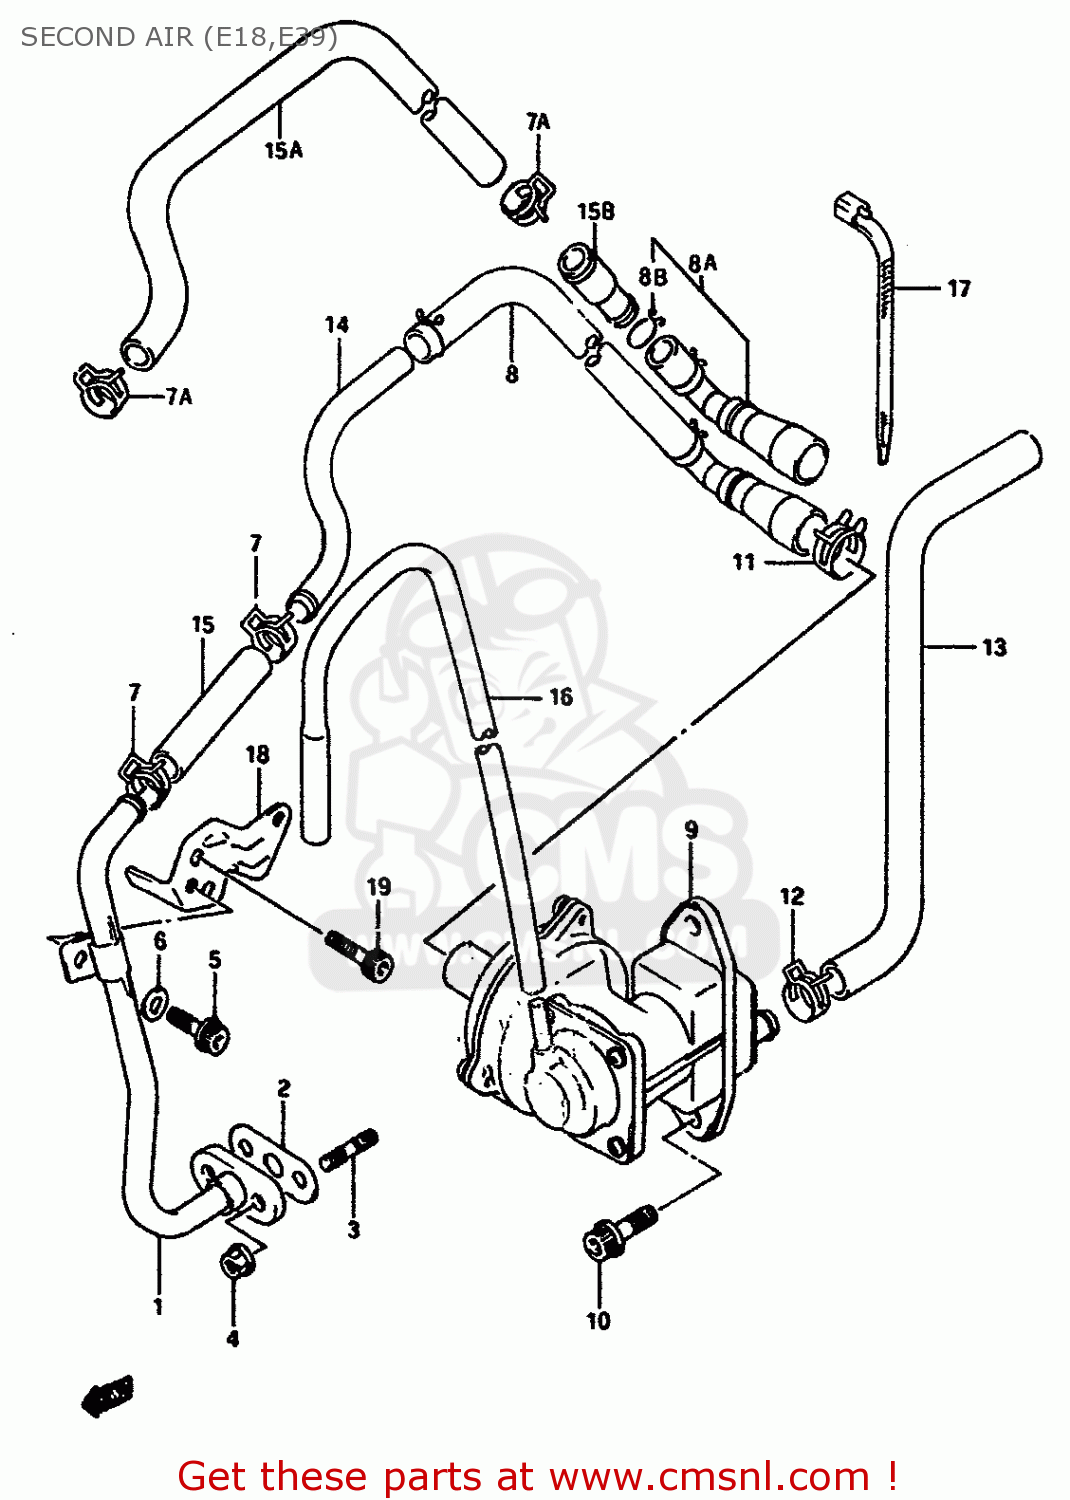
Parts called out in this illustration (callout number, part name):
1	PIPE,2ND AIR
2	GASKET
3	STUD 6X16
4	NUT 6MM
5	BOLT
6	WASHER
7	CLIP
7A	CLIP
8	HOSE ASSY
8A	HOSE ASSY
8B	CLIP,BREATHER TUBE
9	VALVE ASSY,2ND AIR REED
10	PLUG ,6X20
11	CLIP
12	CLIP
13	HOSE,2ND AIR NO.4
14	PIPE,2ND AIR NO.2
15	HOSE,2ND AIR NO.2
15A	HOSE,2ND AIR NO.2
15B	UNION, 2ND AIR HOSE
16	HOSE,2ND AIR NO.3
17	CLAMP(L:165)
18	BRACKET,OIL COOLER UPR
19	PLUG, HEAD COVER
